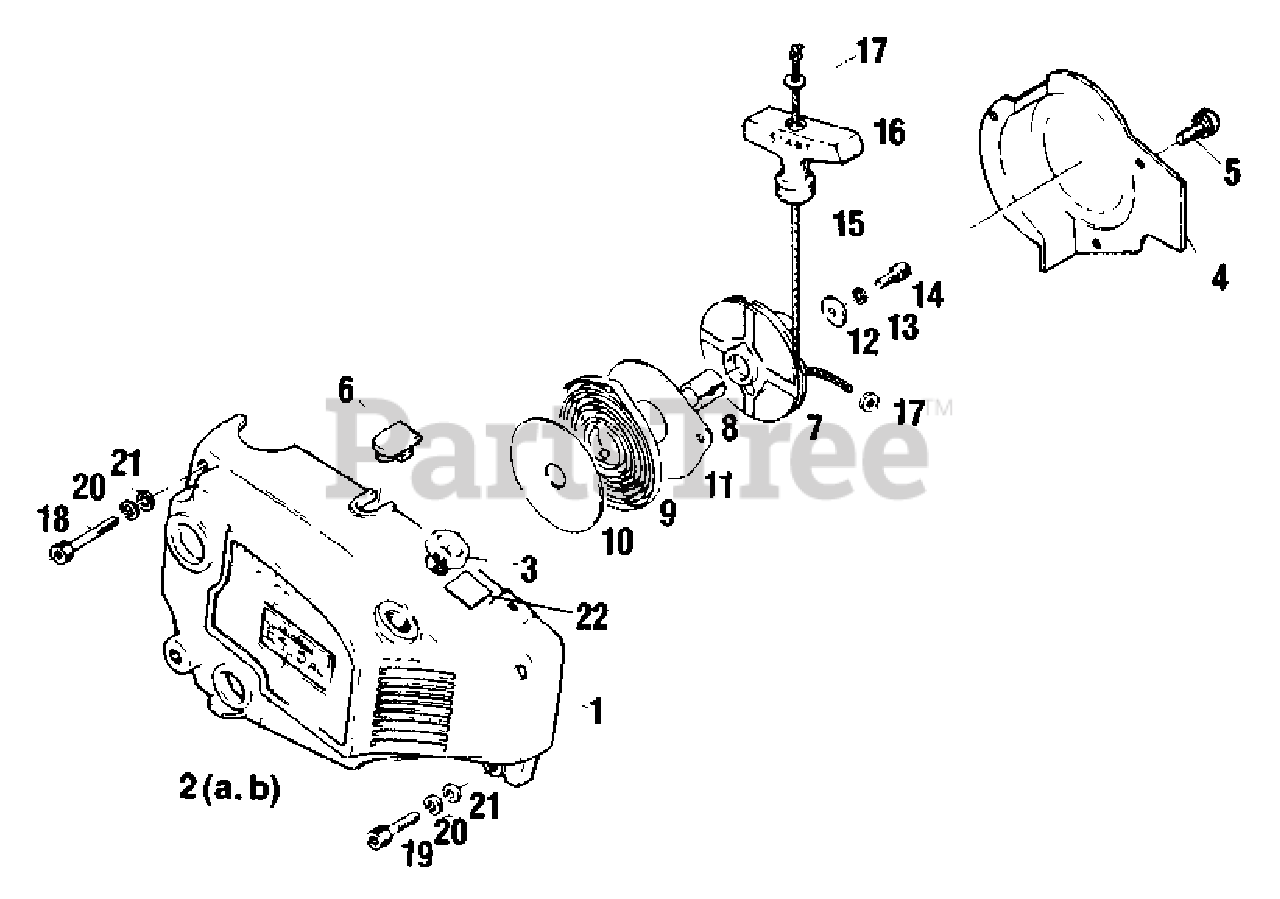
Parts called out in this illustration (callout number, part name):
1	CASE, STARTER
2A	NAME PLATE (B)
2B	NAME PLATE (B)
4	DEFLECTOR, AIR
5	SCREW - 4X8
7	REEL, ROPE
8	BUSHING, REEL
9	SPRING, REWIND
10	PLATE - A
11	PLATE - B
12	WASHER
13	LOCKWASHER - 4
14	SCREW - 4X10
15	ROPE
16	GRIP, STARTER
17	KNOB, STOPPER
18	SCREW - 4X35
19	SCREW - 4X24
20	LOCKWASHER - 4
21	WASHER - 4
22	CAUTION PLATE (A)
